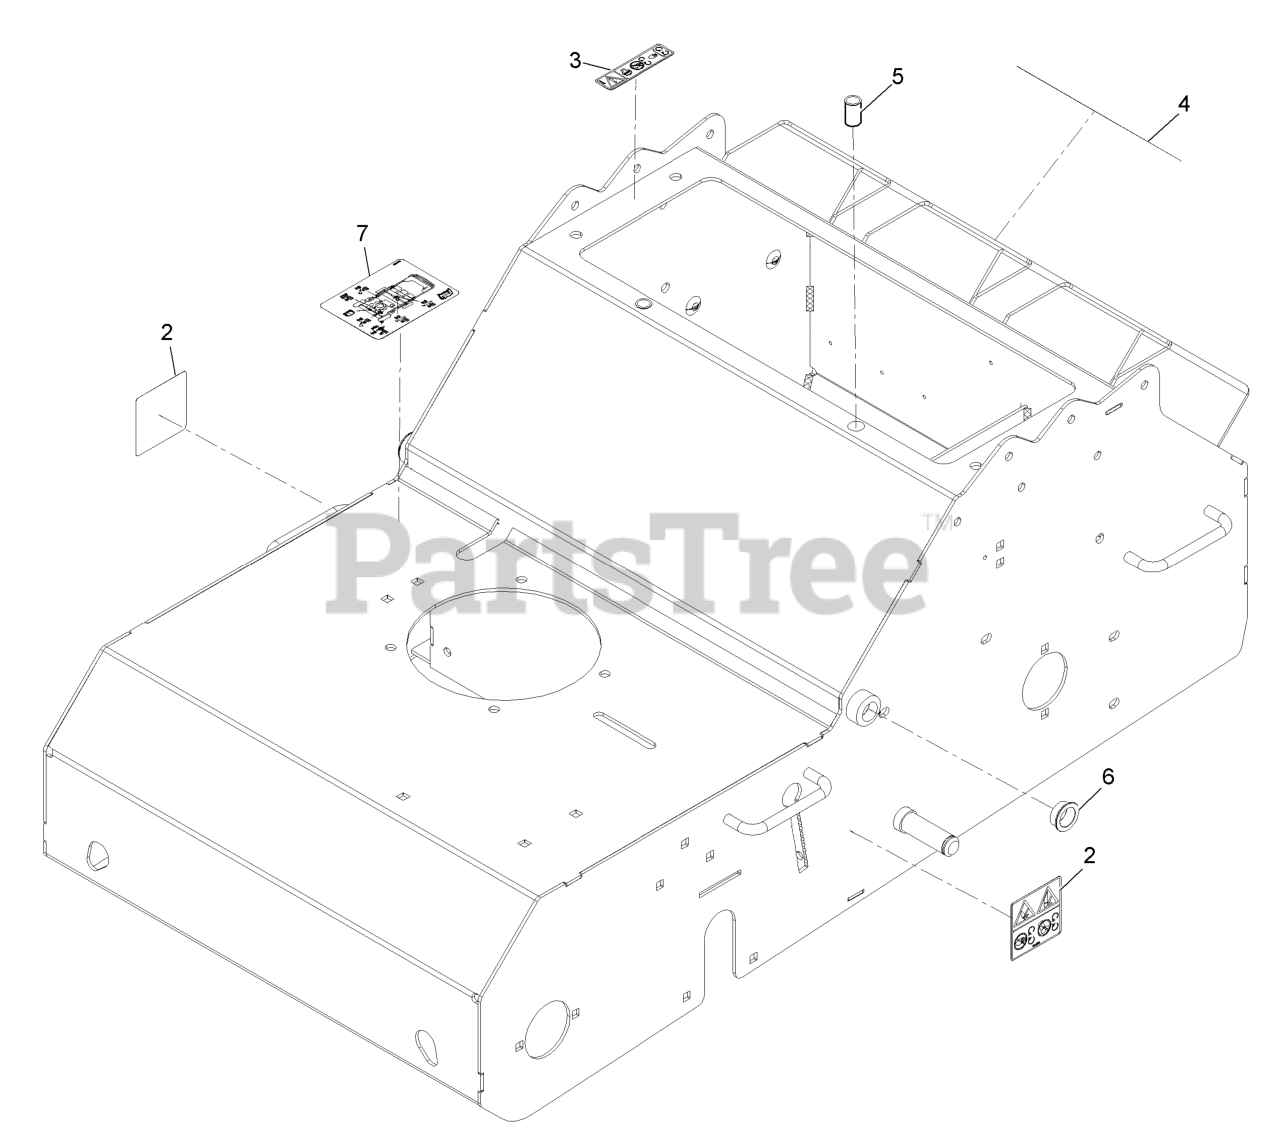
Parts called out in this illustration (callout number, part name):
2	DECAL-WARNING
3	DECAL-DANGER
4	Decal-Warning
5	NUT-CLINCH
6	BUSHING-BRONZE
7	Decal-Service Aid
